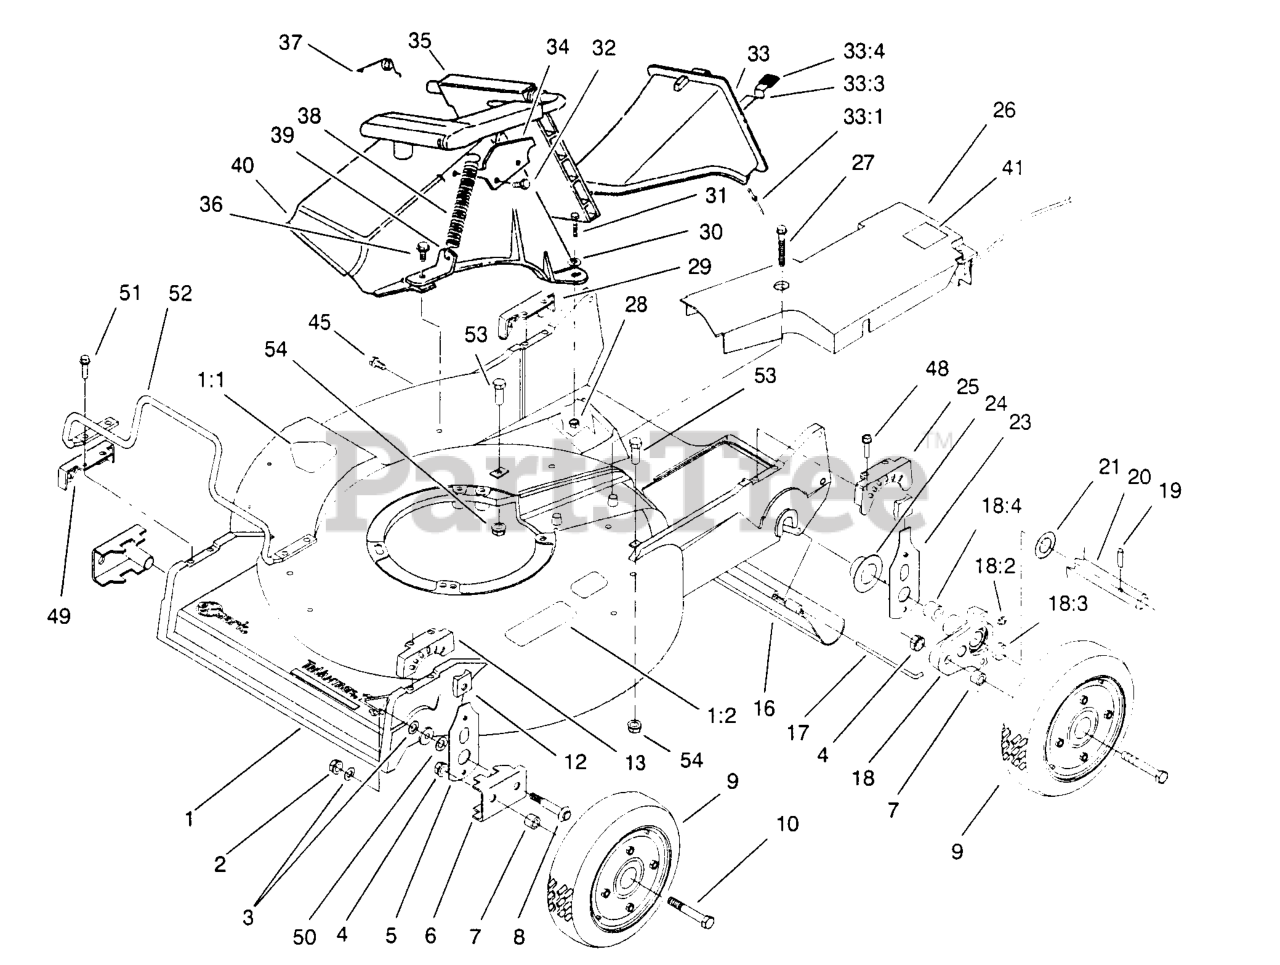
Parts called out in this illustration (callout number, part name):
1:1	DECAL-DANGER
1:2	DECAL-WARNING
2	NUT-LOCK
4	NUT-LOCK, CONE
5	FRONT SPRING ARM ASM
6	ARM-PIVOT, FRONT
7	SPACER-WHEEL
10	BOLT-CARR
12	KNOB-ARM
13	QUADRANT-FRONT, LH
17	ROD-SHIELD
18	PIVOT ARM ASM
18:2	FITTING-GREASE
18:3	BUSHING
18:4	BUSHING
19	PIN-SPIROL
20	SHAFT-AXLE, REAR
21	WASHER-PLAIN
23	REAR SPRING ARM ASM
24	CAP-END
25	QUADRANT-REAR, LH
26	COVER-BELT
27	SCREW-HWH
28	NUT-LOCK, NI
29	QUADRANT-REAR, RH
30	WASHER-FLAT
31	SCREW-HH
32	SCREW-PLASTITE
33	DISCHARGE PLUG ASM
33:1	RIVET-HEAD, FLAT
33:3	LATCH-PLUG, DISCHARGE
33:4	GRIP-LATCH
34	LATCH-PLATE
35	DISCHARGE DOOR ASM
36	SCREW-HWH
37	RETAINER-DOOR
38	SPRING-DOOR
39	BRACKET-SPRING
40	TUNNEL-DISCHARGE
41	LABEL-GREASE, HP
45	SCREW AND WASHER ASM
48	SCREW-HWHTF
49	QUADRANT-FRONT, RH
50	WASHER-THRUST
51	SCREW-HWHTF
52	GUARD-ENGINE
53	SCREW-HH
54	NUT-LOCK, NI
